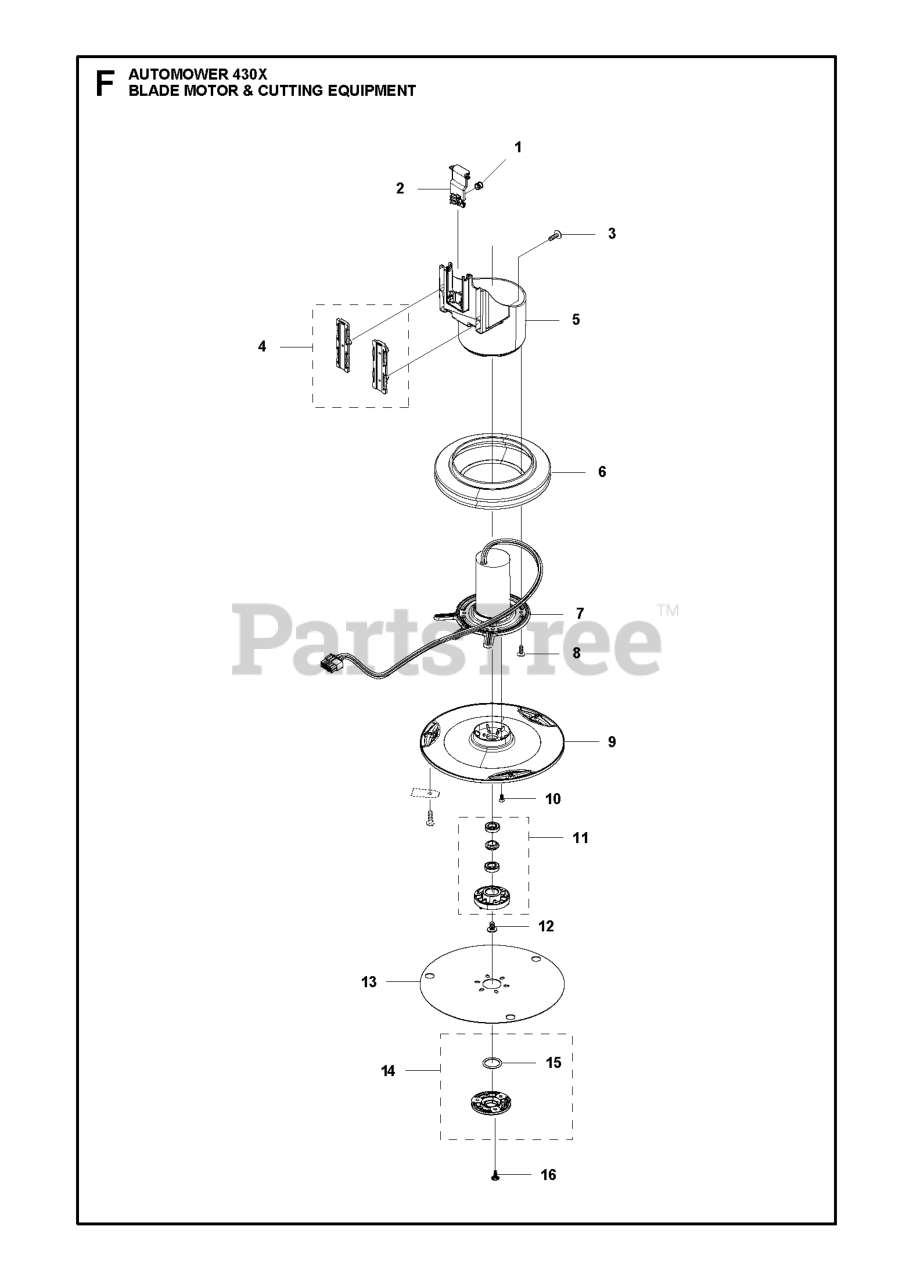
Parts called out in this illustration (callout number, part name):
1	WHEEL.STEERING.LEGEND2.GRY
2	AXLE.CAST.IRON
4	SPINDLE.WELDED.LH.15"TEX
5	SPINDLE.WELDED.RH.15"T
6	THRUST WASHER
9	CAP.SPINDLE.BLACK
14	WASHER, LOCK 3/8
15	NUT CROWNLOCK 3/8-24
16	SHAFT STEERING
19	PLATE.STEER.DDL.NLT/NG
20	BOOT, STEERING
21	ADAPTER, WHEEL STNG..
22	BUSHING.ASM.STEERING.A
26	INSERT.CAP.STRG.WH.GRAY
28	SCREW, 3/8-16X3/4
33	WASHER.LOCK.HVY.HLCL.SPR.5/16
35	GEAR.SECTOR.PLATE.DDL.
45	WASHER.11/32
53	WASHER.HARDENED
57	BRACKET.UPSTOP.TEX
58	BOLT.SHOULDER.SECTOR.P
59	WASHER.THURST.SECTOR.S
60	NUT FLANGE LOCK 5/8-11
61	DRAGLINK.LH.BALLSTUD.D
62	DRAGLINK.RH.BALLSTUD.D
63	SCREW
64	RETAINER.CLIP.SPRING.S
66	BOLT HEX FGHD 7/16-14 X 3 SERR
67	BUSHING.PM.FRONT AXLE
68	NUT.LOCK.FLANGE.7/16
70	BRKT.DECK.SUSPENSION.F
71	SHAFT EXTENSION STEERING
72	BOLT YT
73	WASHER.1.5X.505X.118
